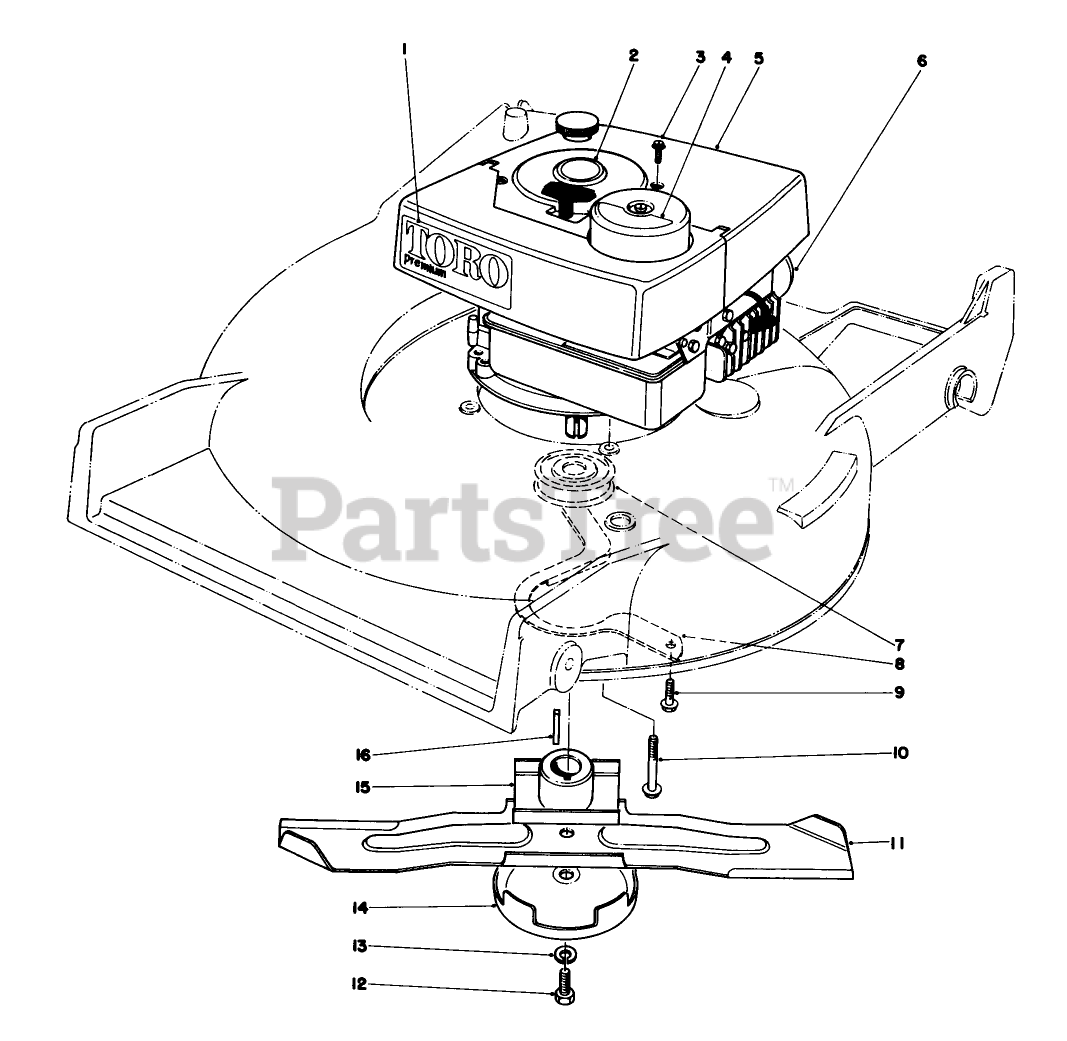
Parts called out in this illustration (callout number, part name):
1	Decal
2	Decal-Shroud
3	Screw
4	Decal Air Filter
5	SHROUD
6	Engine
7	DRIVER PULLEY
8	BELT GUIDE
9	Screw
10	SCREW-HWHTF
11	Blade
12	SCREW-BLADE
13	WASHER-LOCK
14	AntiScalp Cup
15	Blade Retainer
16	KEY-SQUARE
